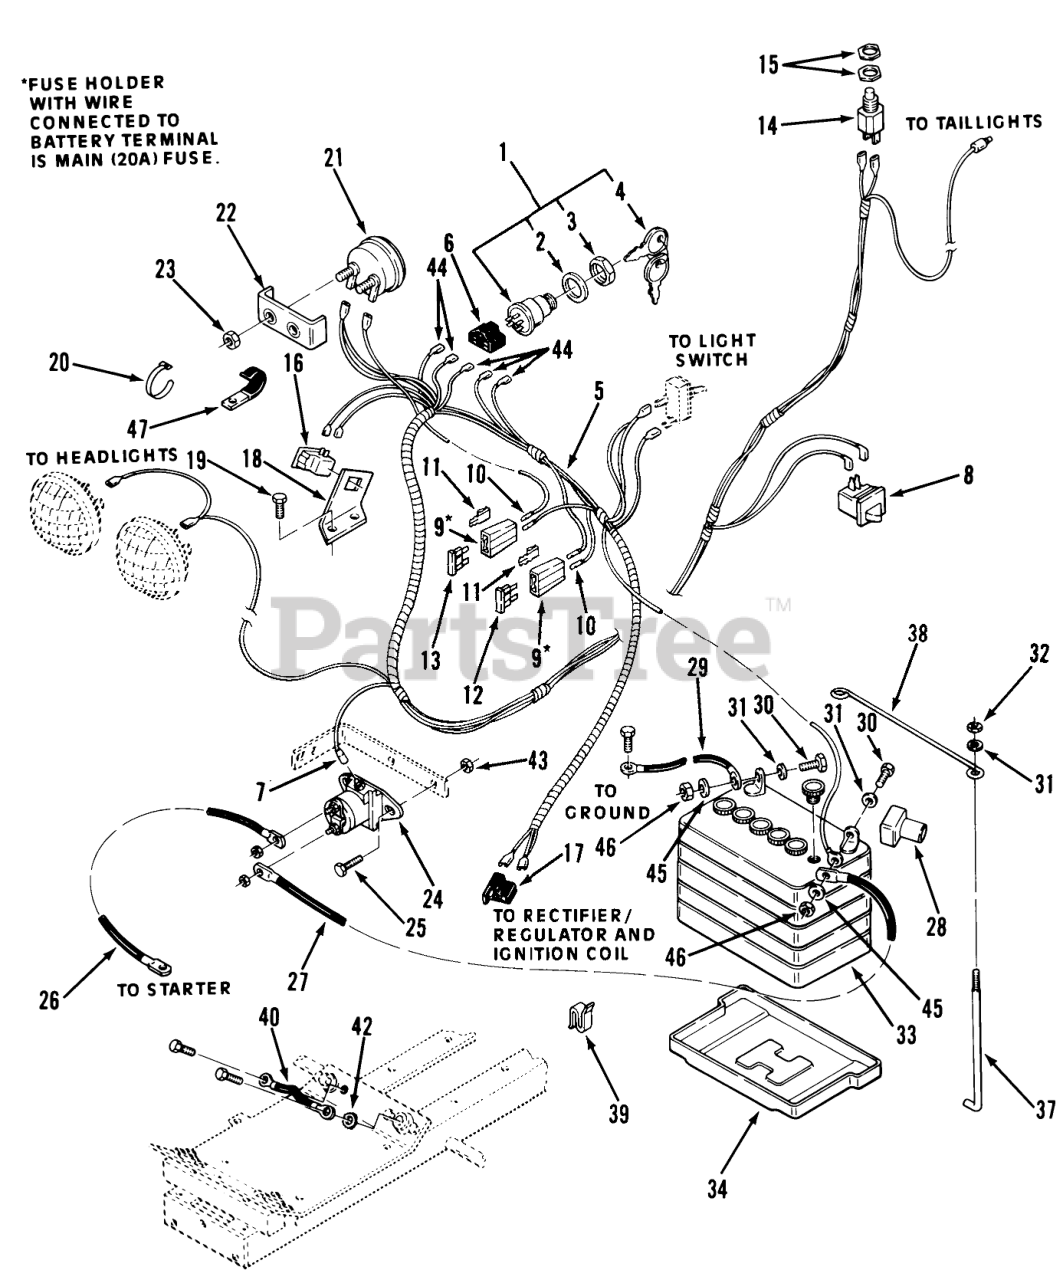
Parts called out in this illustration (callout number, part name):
1	SWITCH-IGNITION
2	LOCKWASHER
4	Key-EL
5	Wiring Harness.
6	CONNECTOR-5 WAY-SERV
7	Terminal Part of 5
8	SWITCH INTERLOCK
9	AUTO-FUSEBLOCK TERM
10	TERMINAL-FUSE
12	FUSE-BLADE, 15 AMP
13	FUSE-BLADE, 25 AMP
14	SWITCH
15	NUT-HEX
16	SWITCH INTERLOCK
17	CONNECTOR BODY
18	BRACKET-SWITCH (NS)
19	Bolt
20	PLASTIC TIE
21	AMMETER W/CLAMP
22	Clamp
23	HEX NUT 10-32 E.S.
24	Solenoid
25	Screw
26	Cable-Solenoid To Starter
27	Cable
28	Boot
29	Wire
30	Bolt
32	Nut
33	Battery
34	TRAY BATTERY
38	ROD-HOLD DOWN
39	SPEED CLIP
40	WIRE-GROUND
42	LOCKWASHER
43	Nut
44	Terminal
45	Washer
46	Nut
47	CLIP
